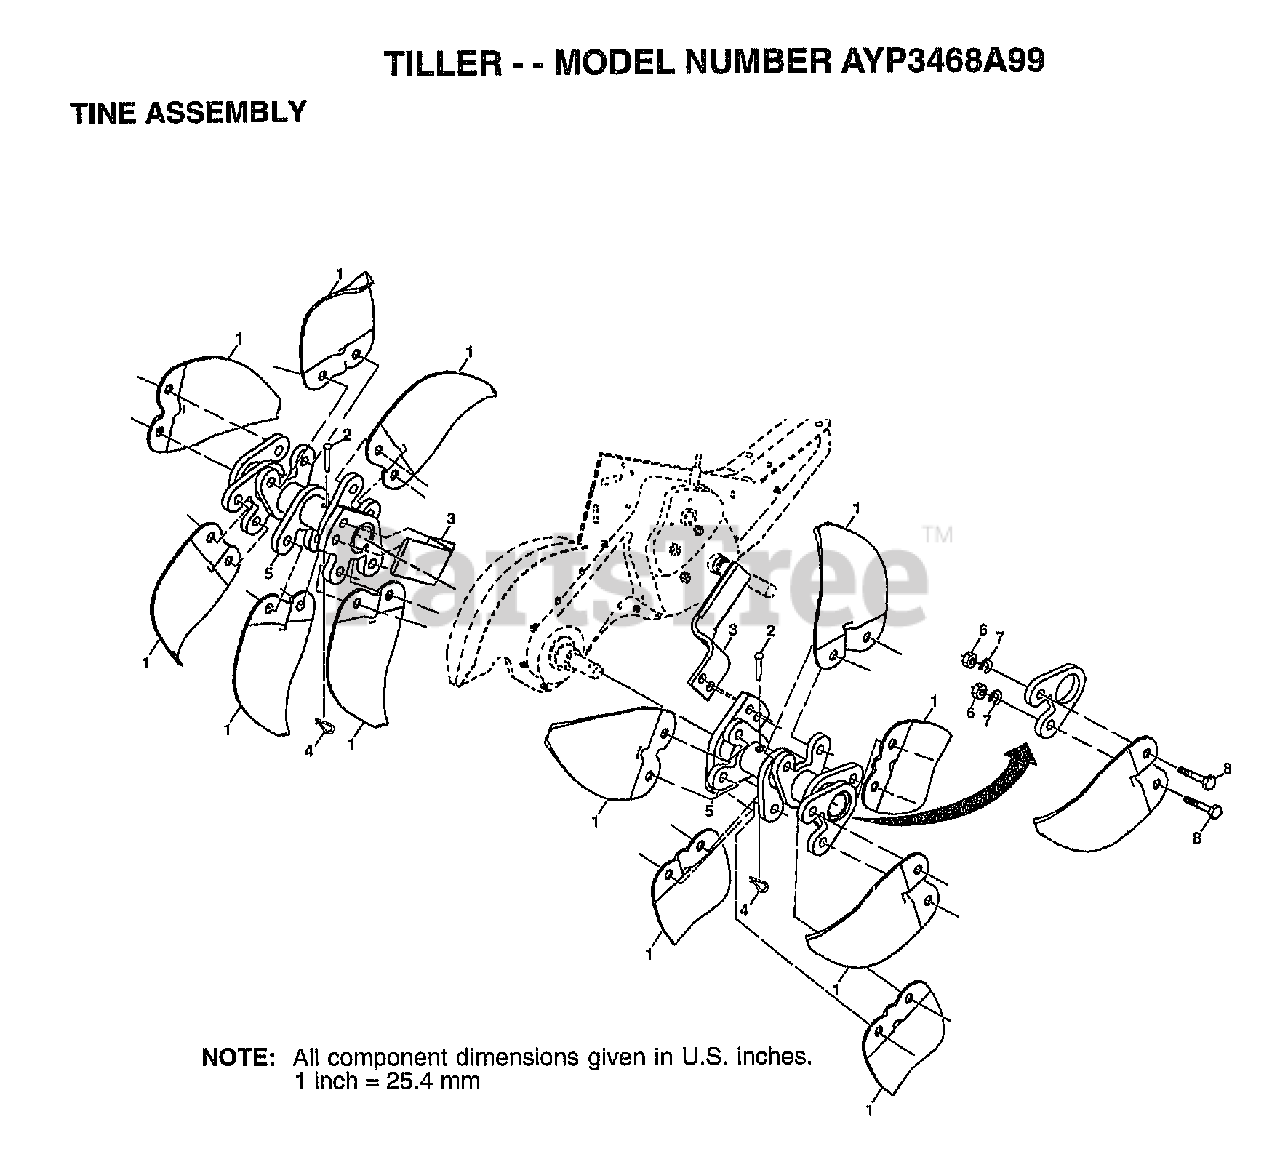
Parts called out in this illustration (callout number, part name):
1	TINE.SPADE
2	PIN.CLEVIS.SHEAR
3	TINE.CLEANING
4	RETAINER SPRING
5	HUB ASM.DRT.19
7	LOCKWASHER
8	BOLT
